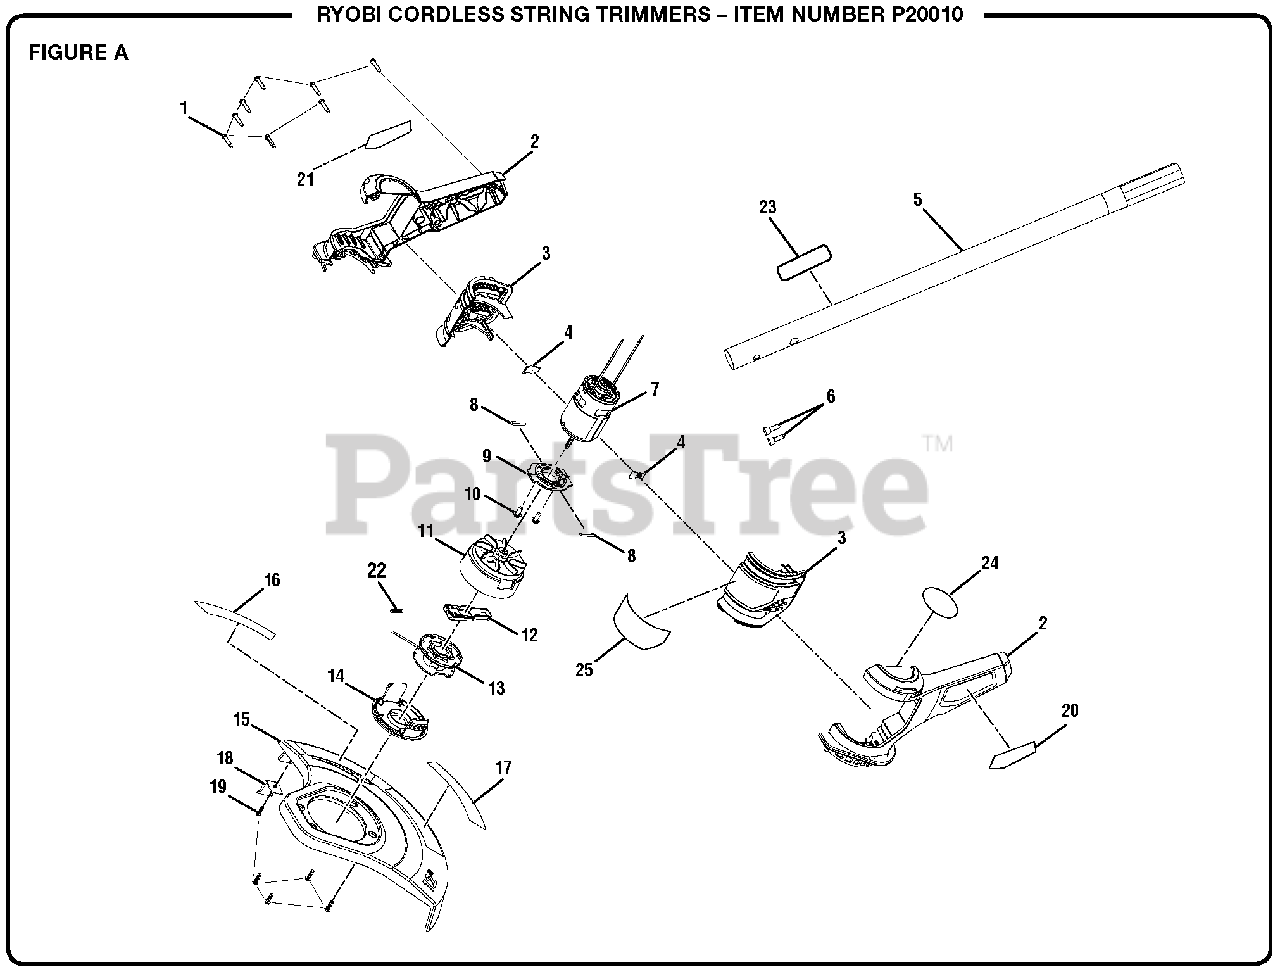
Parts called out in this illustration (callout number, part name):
1	Screw (M4 x 18 mm, Torx. Hd.)
2	Motor Housing Assembly
3	Lower Housing Assembly
4	Motor Rubber Plate
5	Lower Tube Assembly
6	Wire Connector
8	Rubber Plate (Motor Plate)
9	Motor Mounting Plate
10	Screw (M5 x 10.5 mm)
11	Spool Base w/Fan
12	Slider Assembly
13	Spool w/Line Assembly
14	Spool Cap
15	Guard Assembly
16	Adjustable Cut Label
17	Autofeed String Head Label
18	Line Cut-Off Blade
19	Screw (M4 x 12 mm)
20	Left Side Motor Label
21	Right Side Motor Label
22	Compression Spring
23	Lower Boom Lithium Label
24	"R" Badge Label
25	Front Motor Label
